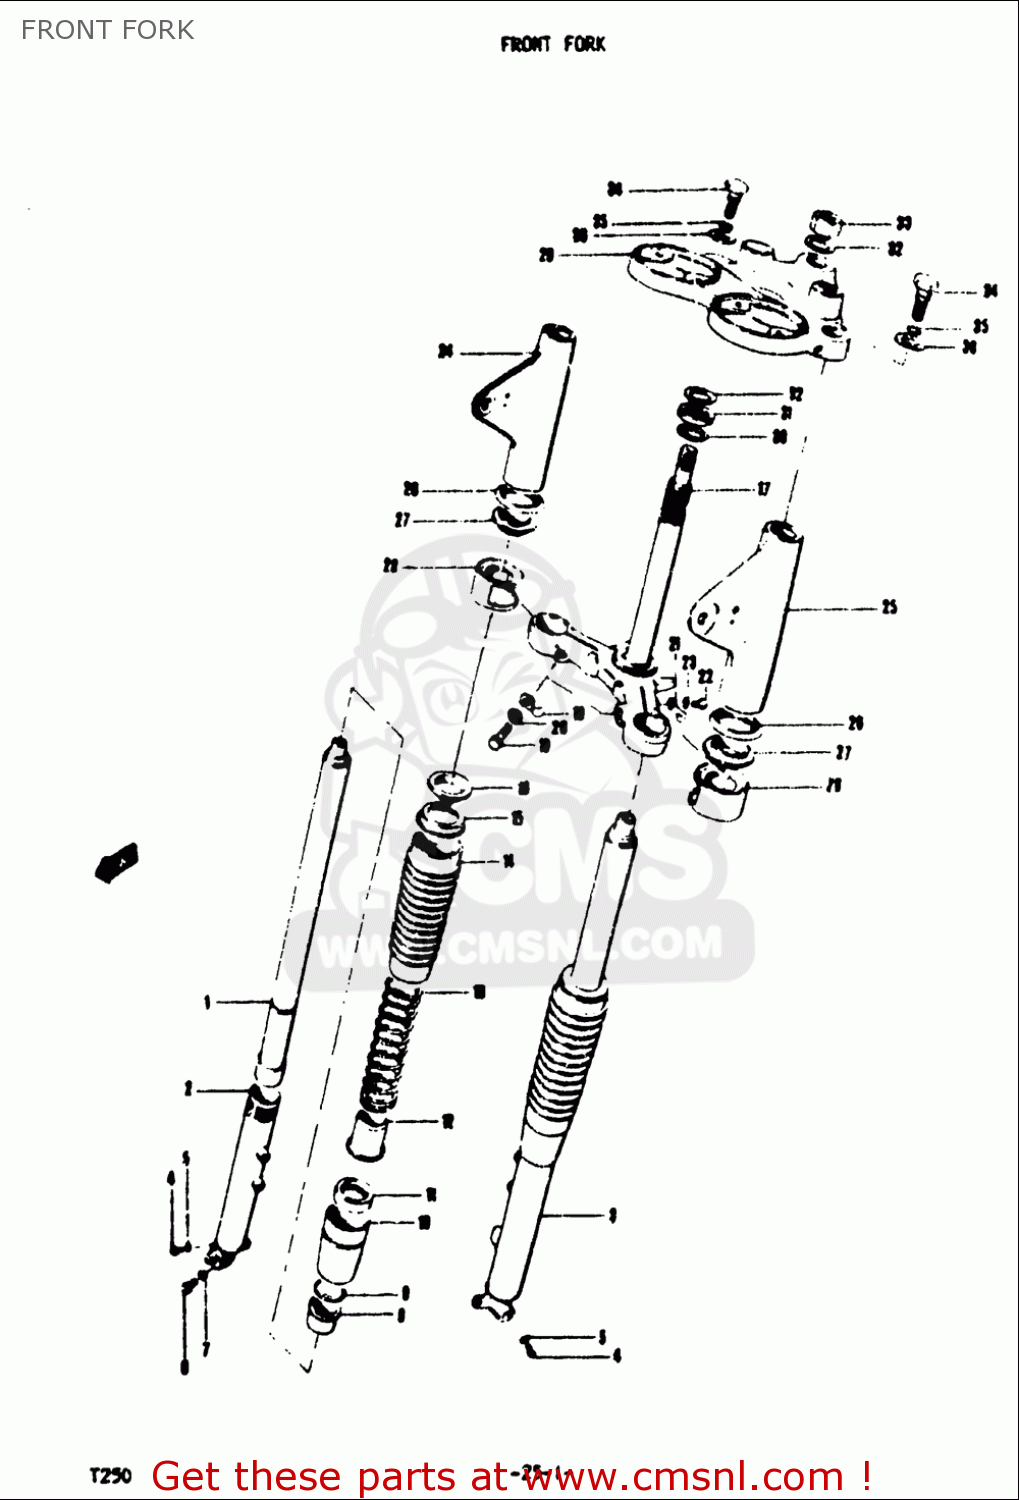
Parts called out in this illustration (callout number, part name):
4	OIL DRAIN PLUG
5	GASKET,DRAIN,PLUG (NAS)
7	WASHER,LOCK
11	SEAL,OIL
14	BOOT,SPRING COVER
18	CLIP,SPEEDOMETER CABLE
20	WASHER,LOCK
21	CLIP,BRAKE CABLE
23	WASHER,LOCK
26	SEAT,HEADLAMP BRACKET
27	CUSHION,HEADLAMP BRACKET
33	NUT
34	CAP,FORK INNER TUBE
36	WASHER
